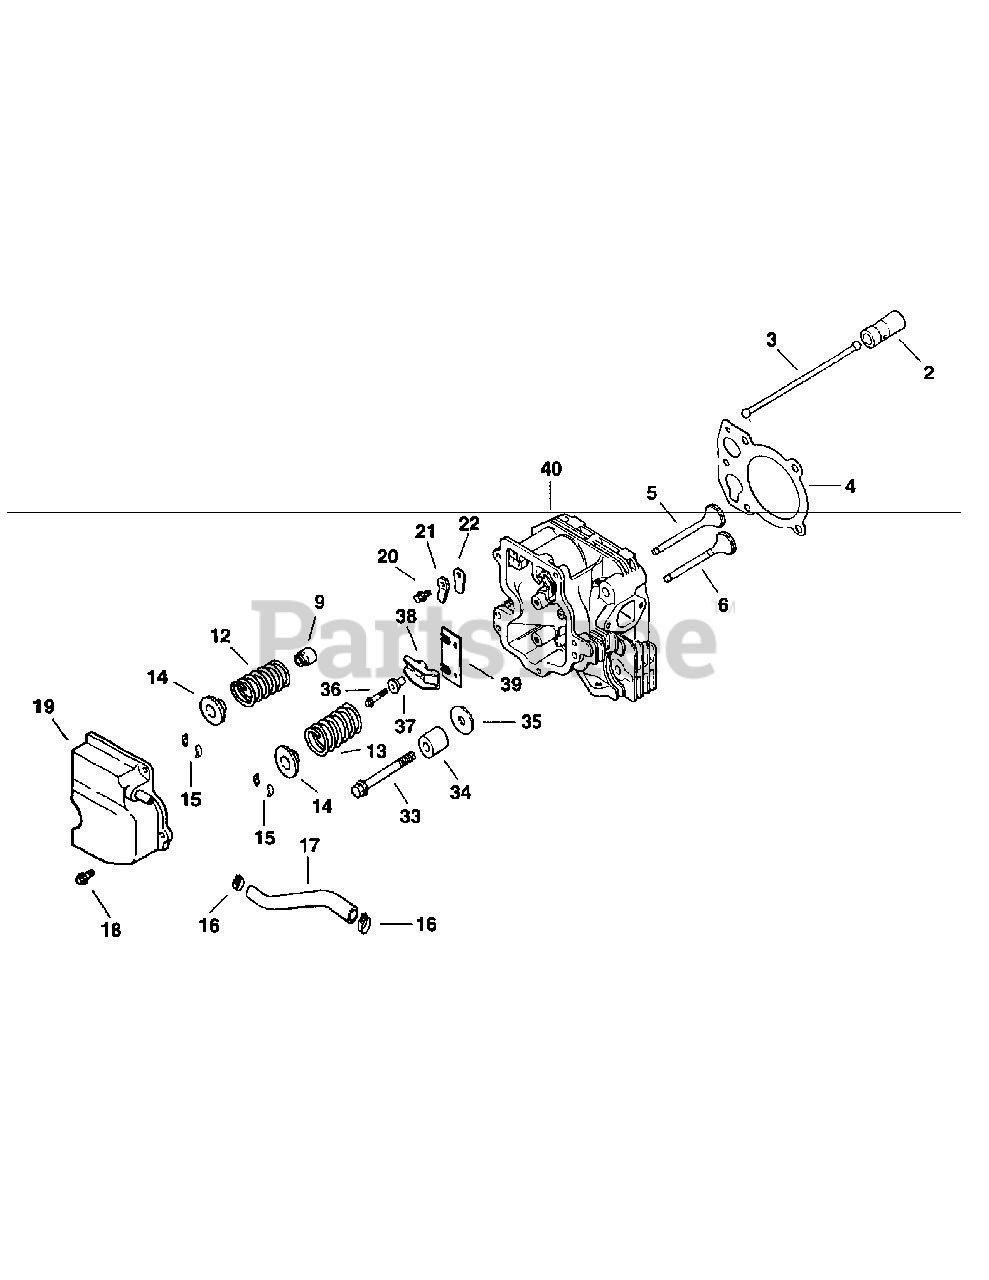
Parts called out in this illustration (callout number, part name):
2	Lifter, Valve
3	Rod, Push
4	Gasket, Cylinder Head
5	Valve, Intake (Std.)
5	Valve, Intake (.25 o.s.)
6	Valve, Exhaust (Std.)
6	Valve, Exhaust (.25 o.s.)
9	Seal, Valve Stem
12	Spring, Intake Valve
13	Spring, Exhaust Valve
14	Cap, Valve Spring
15	Retainer Kit
16	Clamp, Hose
17	Hose, Breather
18	Screw, Hex Flange
19	Cover, Valve w/Nipple
20	Screw, Hex Flange
21	Retainer, Breather Reed
22	Reed, Breather
33	Screw, Hex Flange
34	Spacer, Head Bolt Exhaust Port
35	Washer, Plain 13/32"
36	Screw, Hex Flange
37	Pivot, Rocker Arm
38	Arm, Rocker
39	Plate, Guide
40	Head, Cylinder
